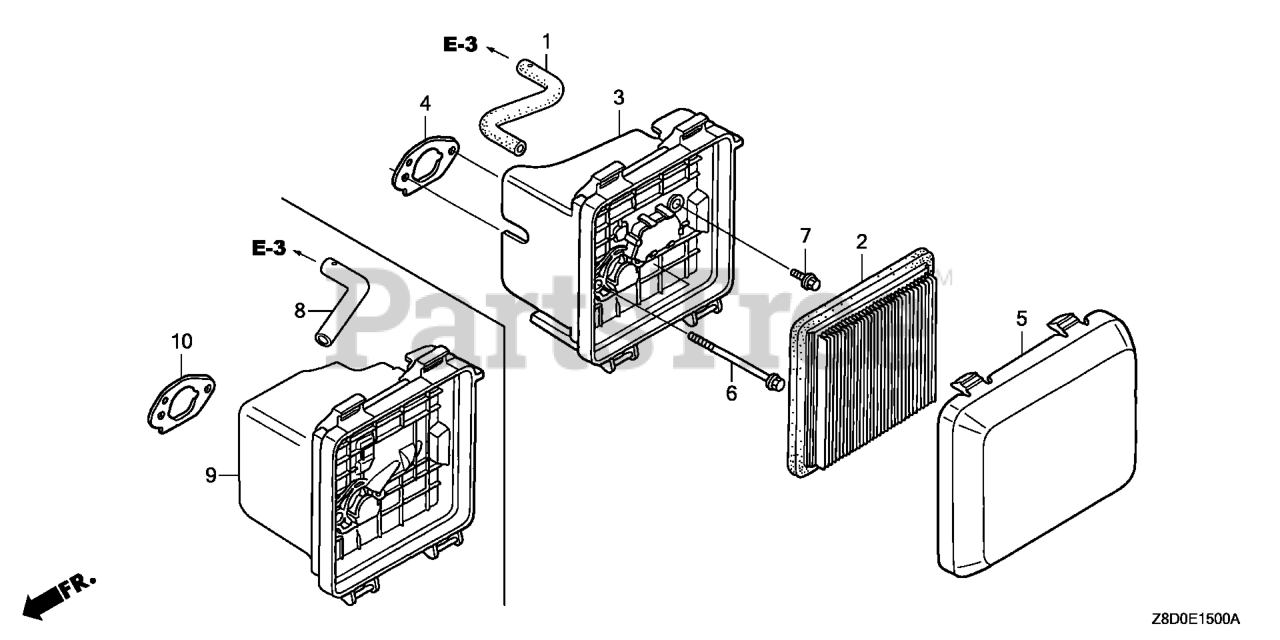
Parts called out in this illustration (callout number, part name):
2	ELEMENT, AIR CLEANER (WIX FILTERS)
5	COVER, AIR CLEANER
6	BOLT, SPECIAL (6MM)
8	TUBE, BREATHER
9	HOUSING, AIR CLEANER
10	GASKET, AIR CLEANER
